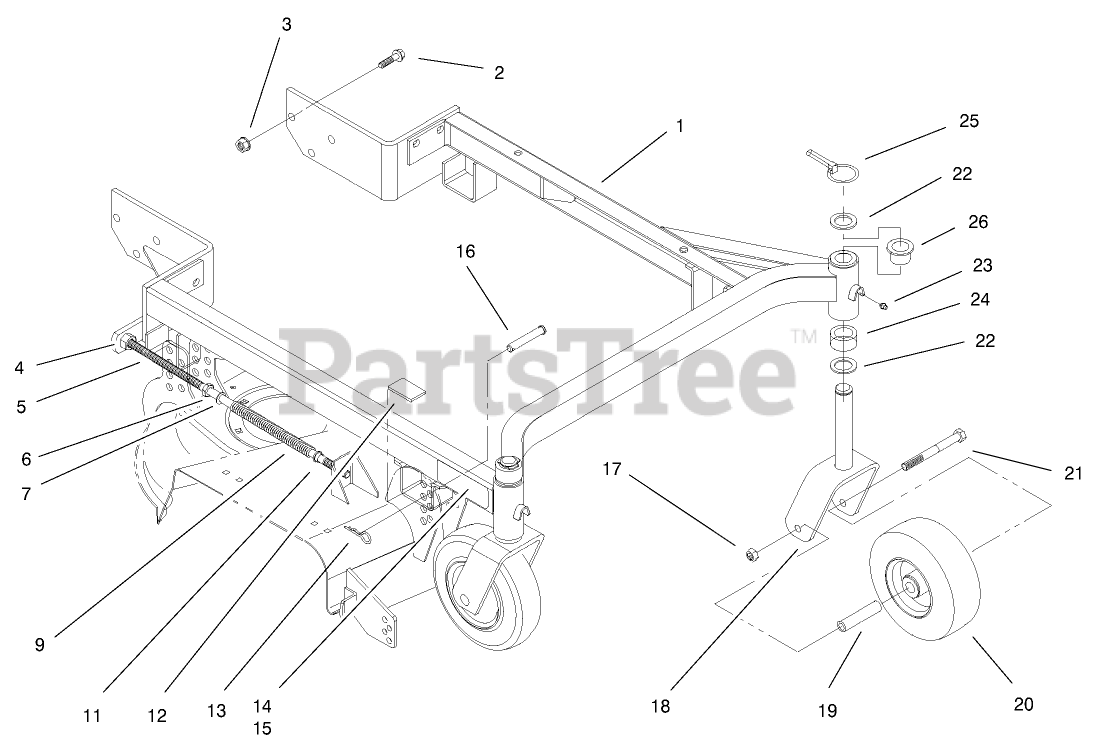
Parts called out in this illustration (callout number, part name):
1	52IN CARRIER FRAME ASM
2	SCREW-HHF
3	NUT-HF
4	NUT-LOCK, NI
5	SHAFT-ADJUSTING
6	NUT-JAM
7	WASHER
9	SPRING
11	BUSHING-FLANGE
12	CUSHION-RUBBER
13	PIN-HAIR
14	DECAL-HOC, LH
15	DECAL-HOC, RH
16	PIN-CLEVIS
17	NUT-HEX
18	CASTOR FORK ASM
19	BUSHING-SPANNER
20	CASTER WHEEL ASM
21	SCREW-HH
22	WASHER-THRUST
23	FITTING-GREASE
24	SPACER-CASTOR
25	Pin
26	BUSHING
